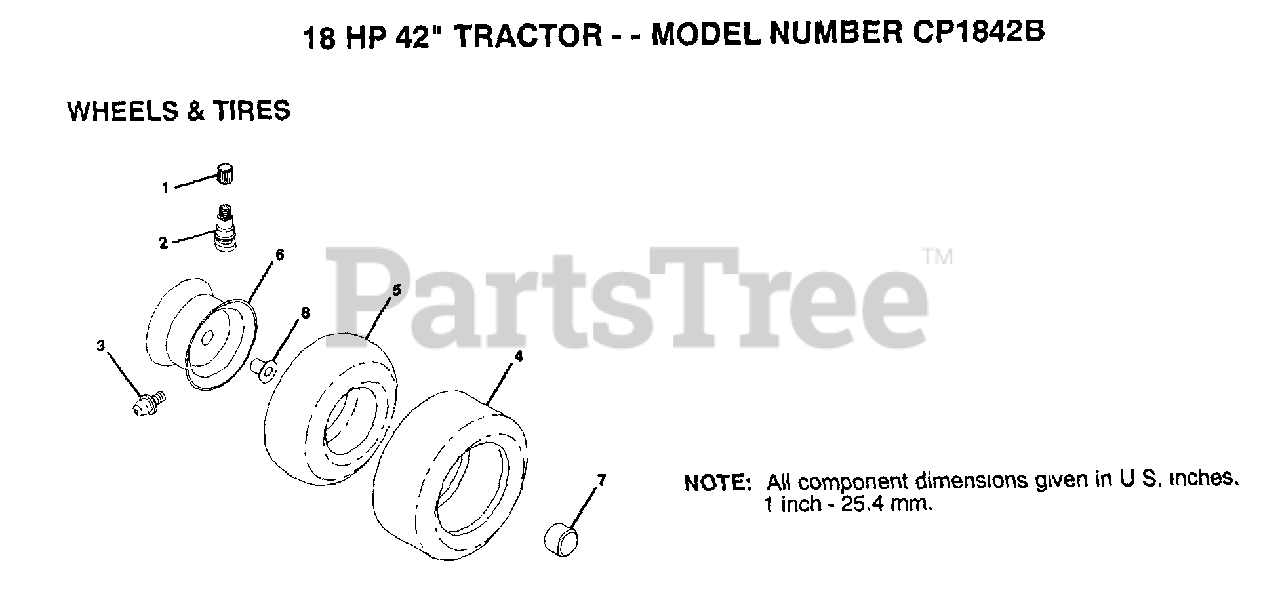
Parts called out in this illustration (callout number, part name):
1	VALVE CAP
2	VALVE STEM LT
3	FITTING LT
4	TIRE TM 15X6X6
4	TIRE TM 20X8X8
5	TUBE.5.3/4.5/6
5	TUBE.18X9.5-8
7	HUB CAP
8	"FLANGE, BEARING"
